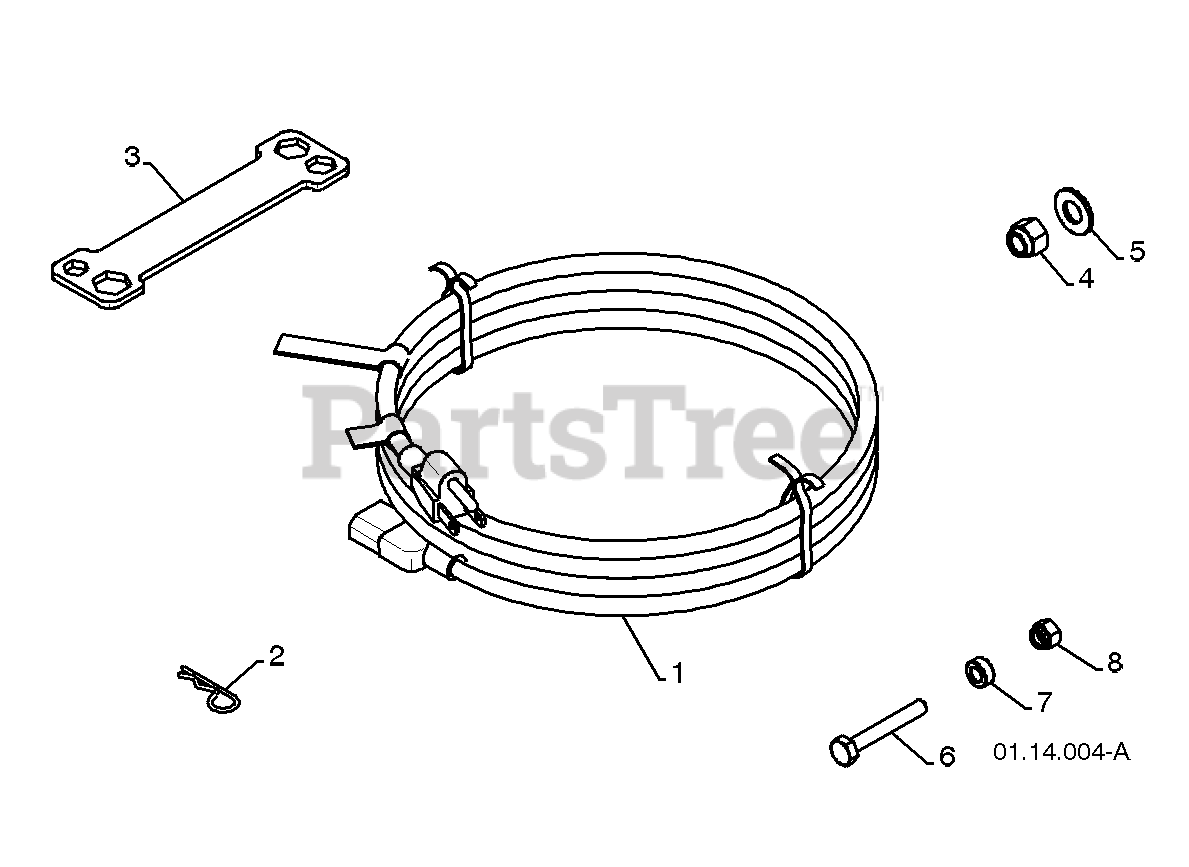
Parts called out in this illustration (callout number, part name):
1	POWER CORD
2	RETAINER PIN
3	WRENCH
4	LOCKNUT 3/8-16
5	WASHER 3/8
6	SHEAR BOLT 1/4-20 X 1-3/4
8	LOCKNUT 1/4-20
